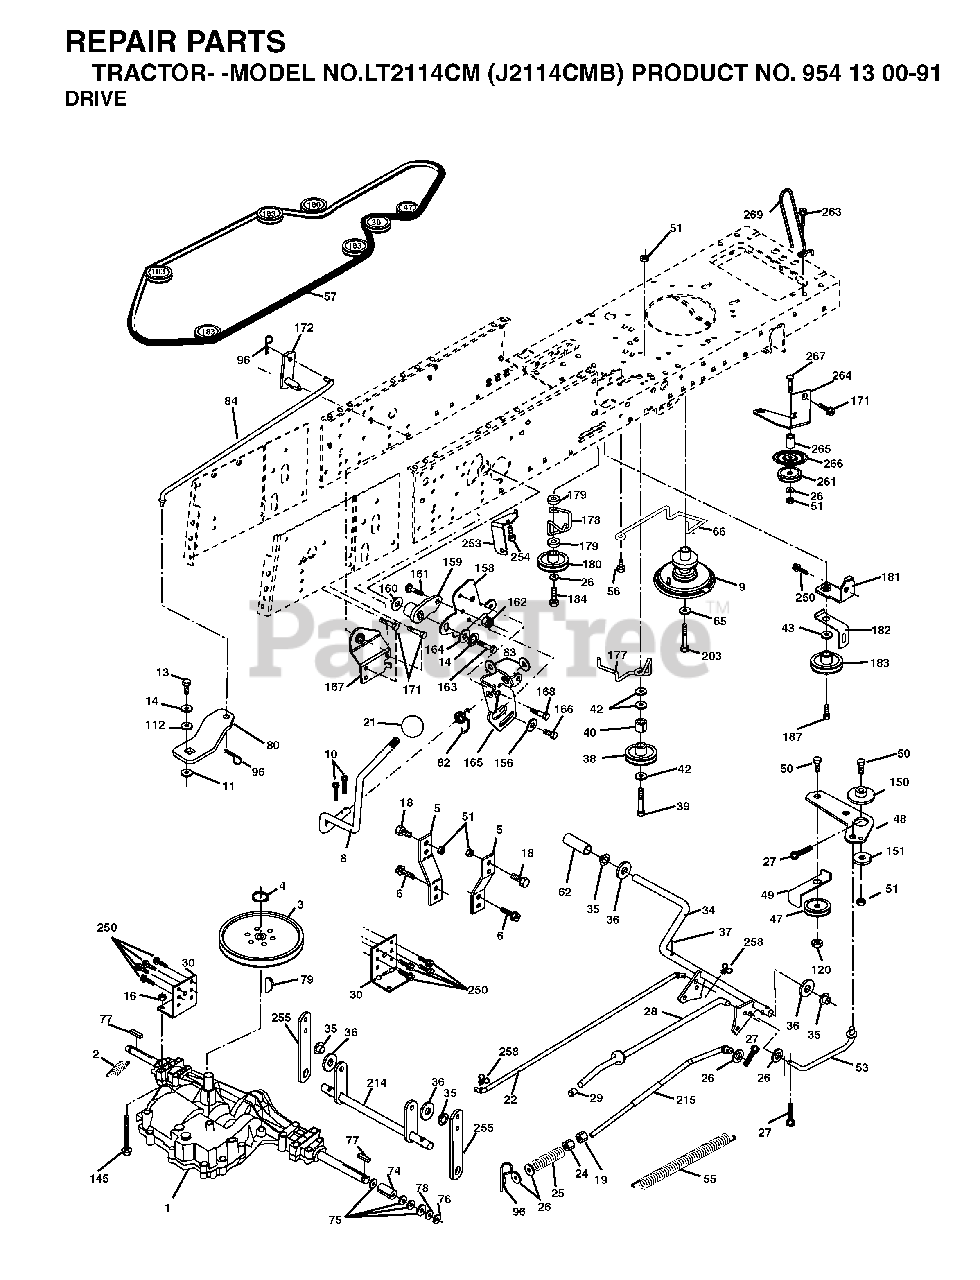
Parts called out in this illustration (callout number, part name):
2	SPRING,BRAKE RETURN
4	RETAINING RING LT
5	STRAP TORQUE
6	SCREW 5/16"
8	ROD SHIFT
10	PIN COTTER
11	WASH-SHFT PLT LT
13	BOLT 1/4-28X3/4
14	LOCKWASHER
16	NUT.71038.31-18.HEX.NYLOCK
19	NUT
21	KNOB T (1/2-HOLE)
24	NUT
25	SPRING ROD LT
27	COTTER PIN
28	ROD, PARKING BRAKE
29	PLUNGER CAP
30	BRKT, MOUNT TRNSAXLE
34	SHAFT, FOOT PEDAL
35	BEARING.NYLON
36	WASHER LT
37	DRIVE PIN
38	PULLEY.FLAT
42	WASHER
47	IDLER PULLEY
48	BELLCRANK, CLUTCH
49	RETAIN BELT
50	BOLT.3/8-16X1.50
51	LOCKNUT
53	LINK, CLUTCH LT
55	SPRING, RETURN LT
56	SCREW.3/8-16
57	V-BELT.KEV.111"
62	PEDAL COVER T
65	LOCKWASHER
66	KEEPER BELT ENGINE
74	SPACER AXLE
76	E-RING LT
77	SQUARE KEY
80	ARM SHIFT
82	SHIFT SPRING
83	WASHER
96	RETAINER M
112	WASHER LT
120	NUT LOCK FLG 3/8-16 UNC
150	BUSHING.BELLCRANK.GRD.DR
151	WASHER 12/32X2X10GA
156	WASHER.SRRTD.5/16
158	BRACKET
159	HUB.SHIFT
161	BOLT
162	NUT.CROWNLOCK.1/4
165	RP BRACKET
167	BRACKET
168	BOLT.SHOULDER.5/16-18X
180	PULLEY.FLAT.IDLER
184	SCREW.HXWSH.3/8
187	BOLT.5/16-18X1.25
250	SCREW 3/8-16X3/4
254	SCREW 3/8-16X1
258	CLIP RETAINER
261	FLAT IDLER PULLEY
263	SCREW, 3/8-16X3/4
265	SPACER IDLER
